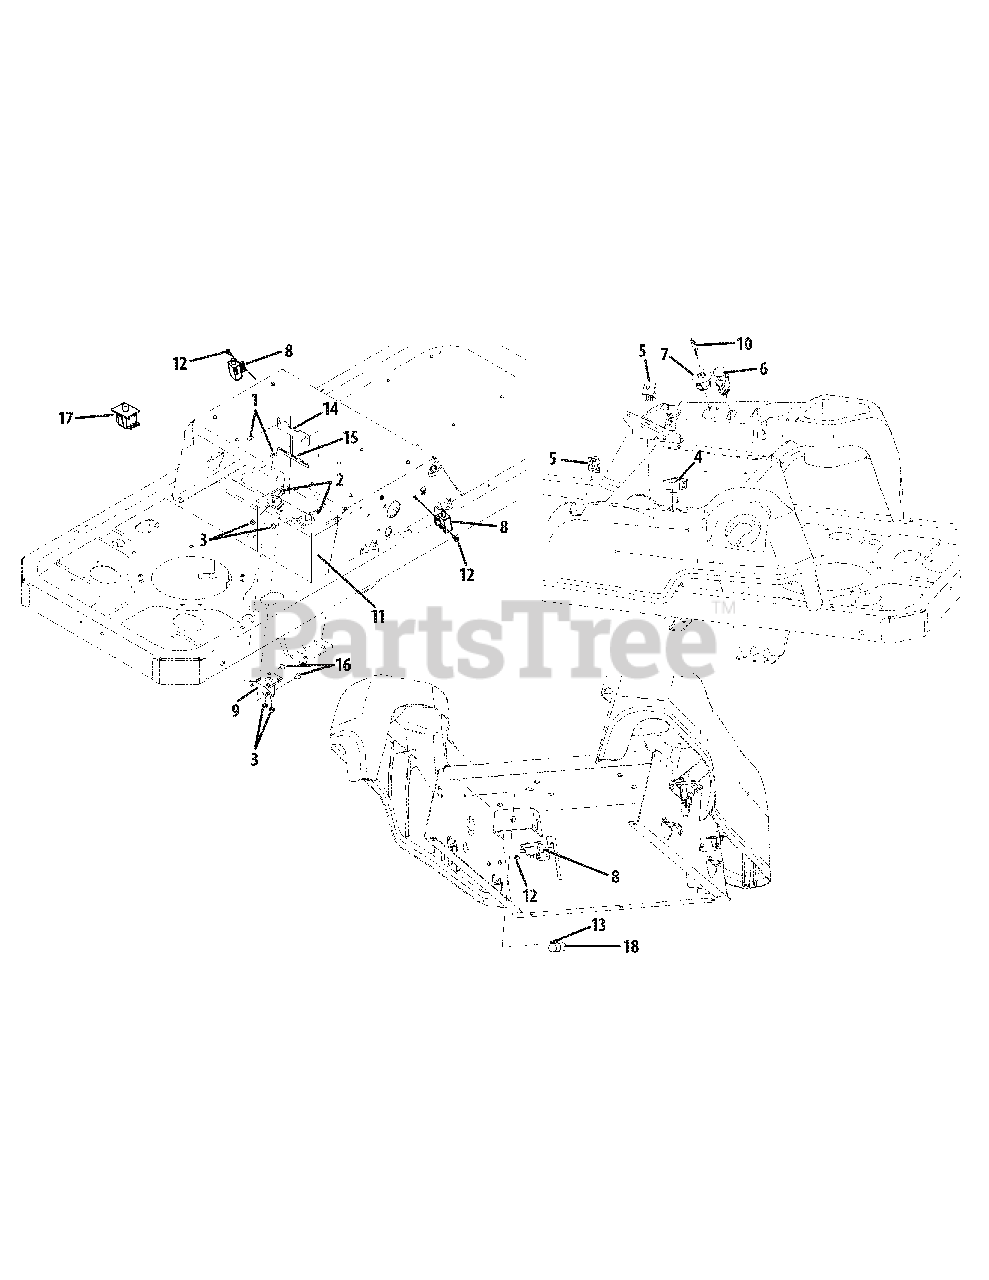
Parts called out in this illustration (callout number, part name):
1	Hex Screw, 1/4-20 x .5
2	Hex Screw, 1/4-20 x .75
3	Hex Nut, 1/4-20
4	Hour Meter
5	Double Pole - Neutral Switch
6	PTO Switch
7	Ignition Switch
8	Interlock Switch
9	Solenoid
11	Battery, 235 CCA
12	Shoulder Screw, #10-32 x .500
13	Cable Tie
14	Battery Hold-down
15	Trim Strip
16	Hex Screw, 1/4-20 x .375
17	Seat Switch
18	Wire Harness
